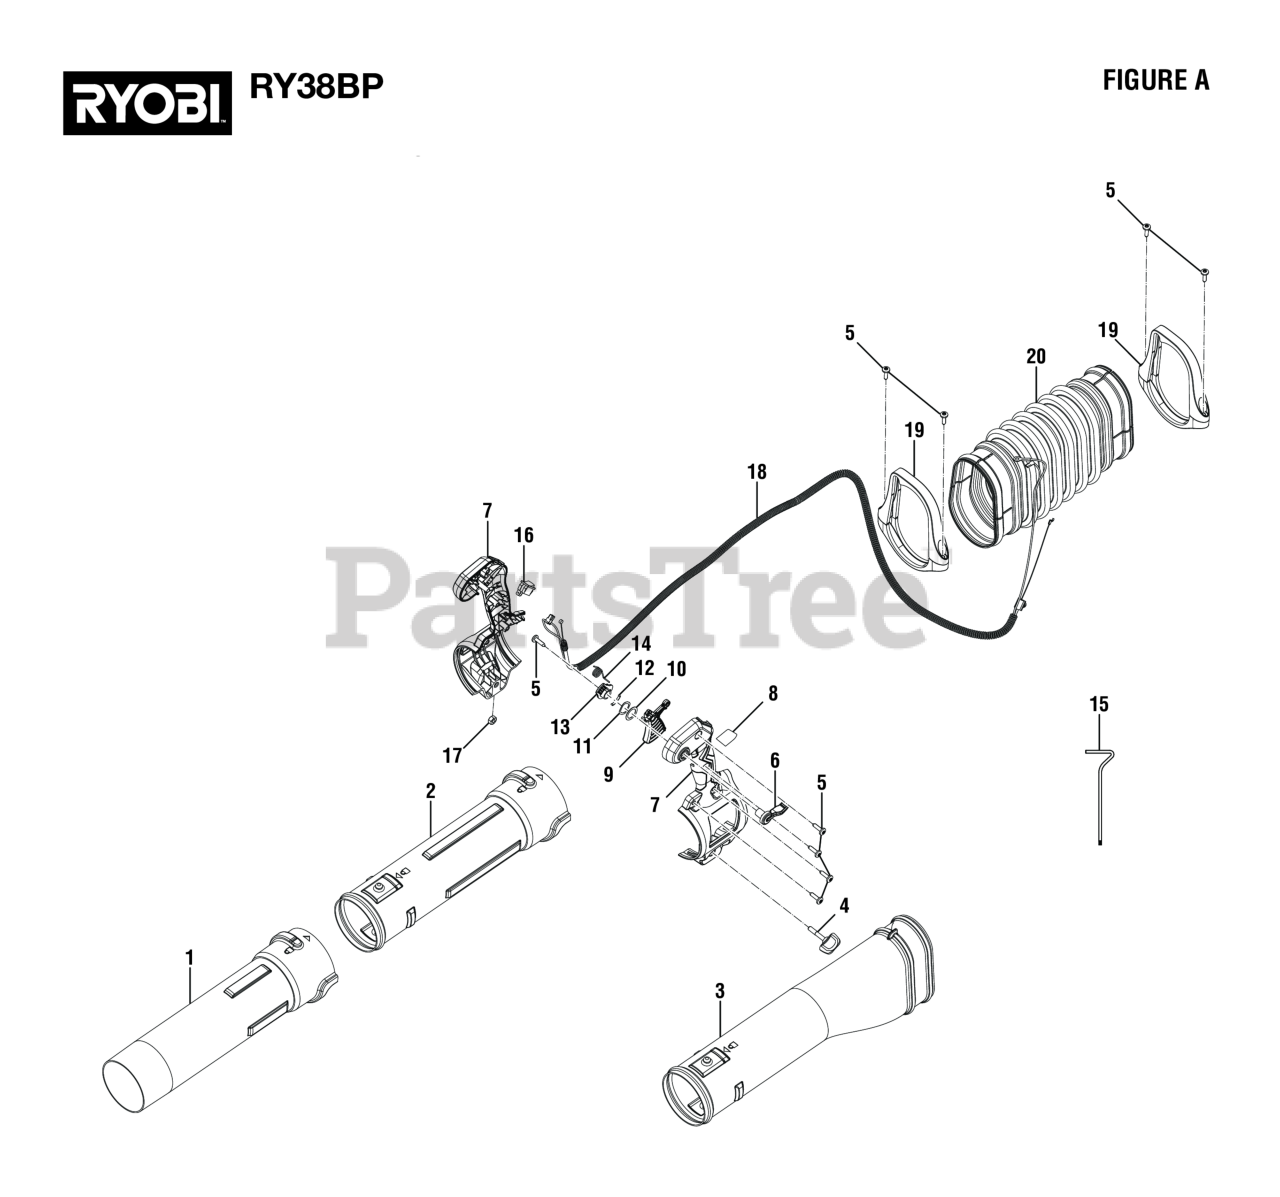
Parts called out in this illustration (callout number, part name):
1	Lower Blower Tube
2	Upper Blower Tube
3	Handle Blower Tube
4	Adjustment Knob (1/4-20 UNC)
5	Screw (10-14 x 19 mm, T25 Torx Truss Pan Hd. T.F.)
6	Cruise Control Lever
7	Handle Half Assembly w/Label
8	Cruise Control Label
9	Throttle Trigger
10	Washer (22.5OD x 16ID x 0.5t)
11	Wavy Washer (217OD x 165ID x 15t)
12	Detent Spring
13	Cruise Control Actuator
14	Torsion Spring (Throttle Trigger)
15	Assembly Wrench (T25)
16	Stop Switch (Momentary Contact)
17	Hex Nut (1/4 - 20)
18	Throttle Cable and Wire Assembly
19	Bellows Clamp Assembly
20	Bellows Tube
